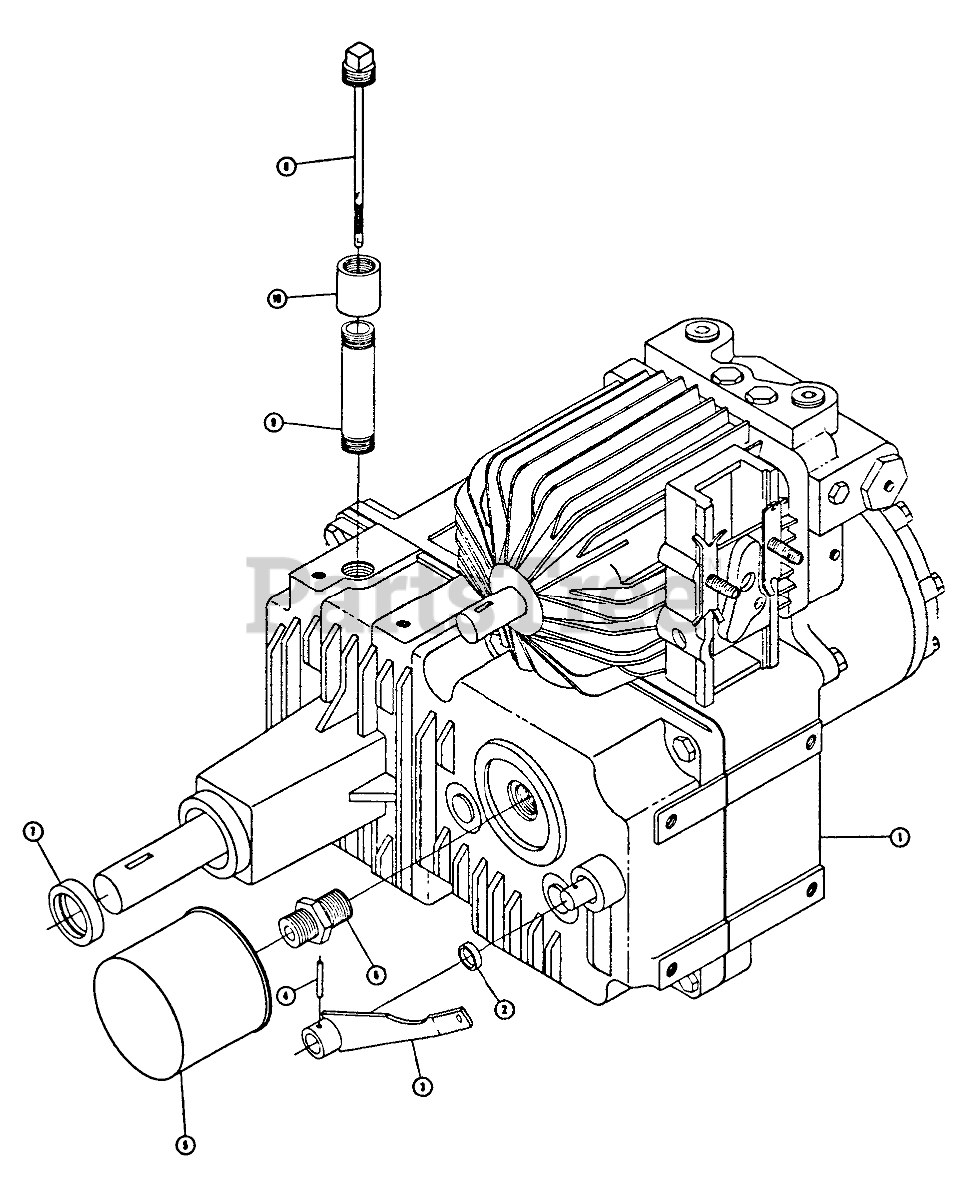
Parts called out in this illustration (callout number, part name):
1	Ass-y. Transmission Complete
6	FITTING
10	Coupling 1/2 Pipe
